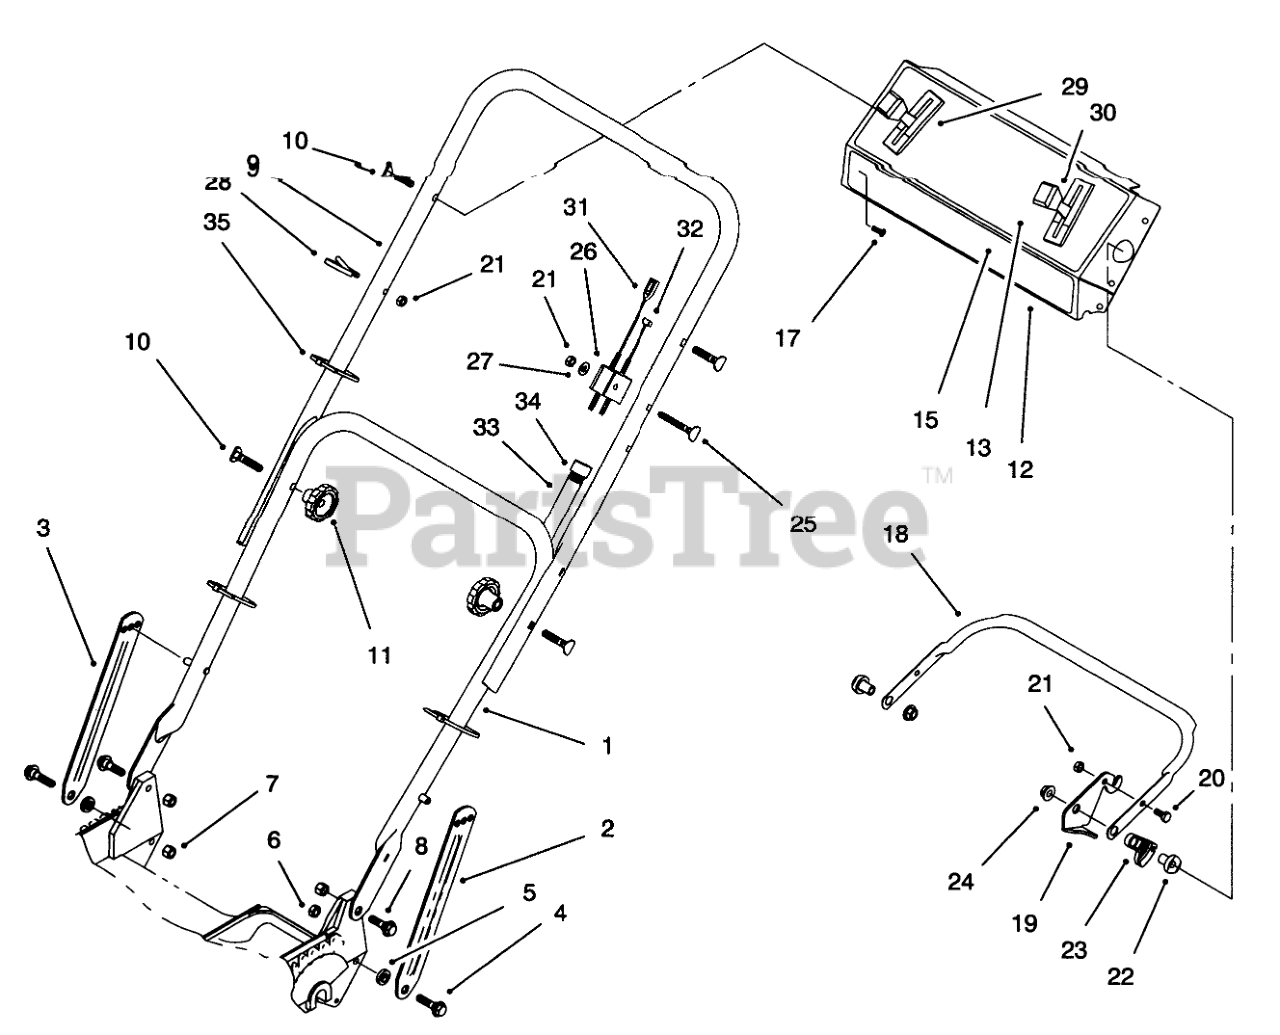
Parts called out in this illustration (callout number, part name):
1	ASM-Handle
2	Latch-Handle
3	Latch-Handle
4	SCREW-SHOULDER
5	SPACER
6	NUT-LOCK, NI
7	NUT-LOCK, NI
8	SCREW-SHOULDER
9	Handle-Upper
10	SCREW-HANDLE
12	Panel-Control (Incl. Ref. #13)
13	DECAL - INSTRUCTION
15	DECAL - CONSOLE
17	SCREW-TAP
18	Bar-Control
19	Lever-Control
20	SCREW-HH
21	NUT-LOCK, NI
22	SPACER-SUPPORT
23	LEVER-TRACTION
24	NUT-LOCK NI
25	SCREW-HANDLE
26	SUPPORT-CABLE
27	WASHER-FLAT
28	GUIDE-ROPE
29	CONTROL-SPEED, GROUND
30	CABLE - THROTTLE
31	CABLE - BRAKE
32	CABLE-TRACTION
33	CONTROL CABLE COVER
34	FITTING-RING
35	TIE-CABLE
